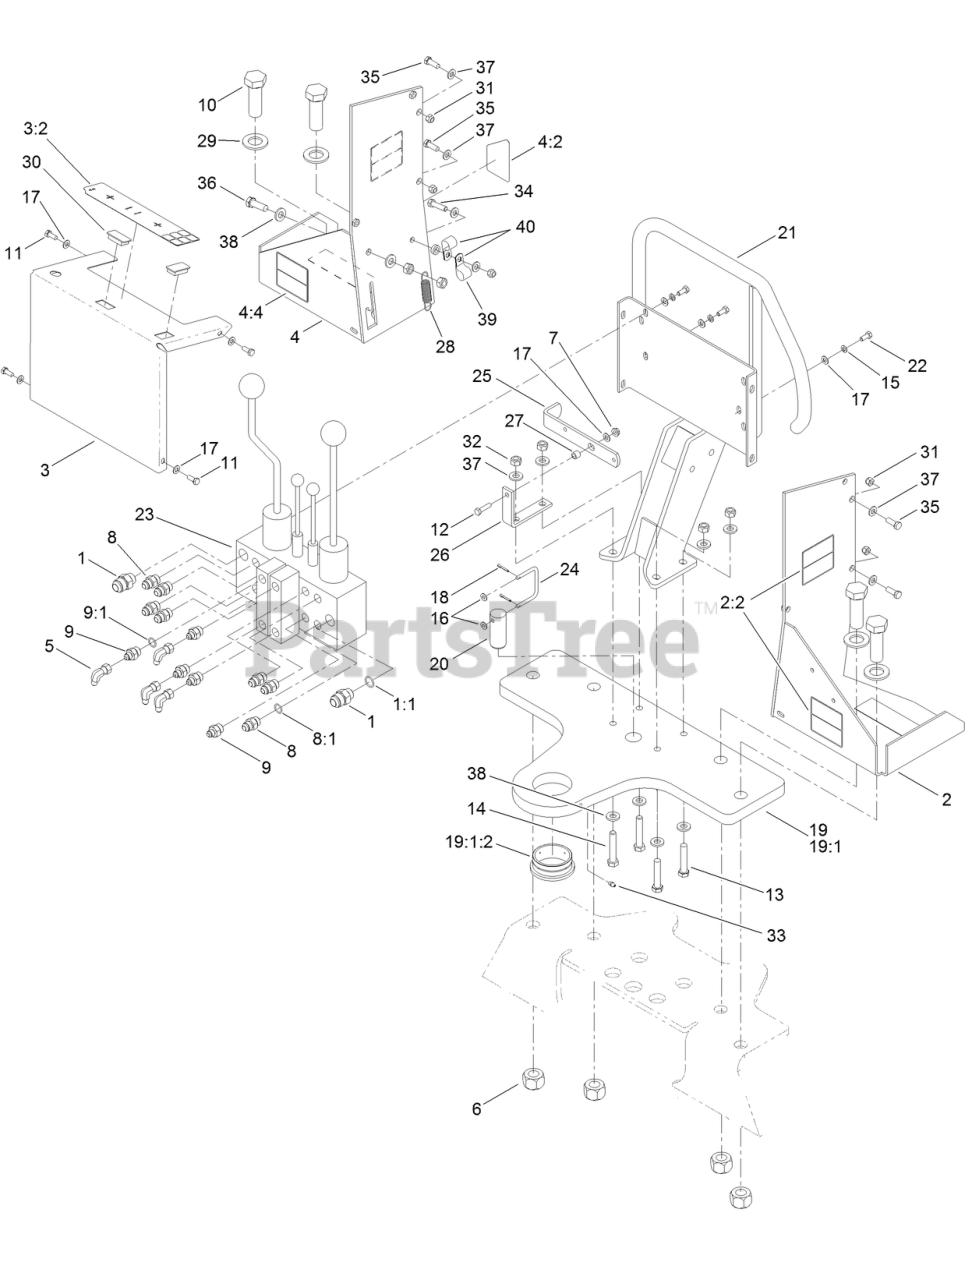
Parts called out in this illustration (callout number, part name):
1	FITTING-STRAIGHT
1:1	O-RING
2	LH FOOT GUARD AND DECAL ASM
2:2	DECAL-DANGER, CRUSHING
3	VALVE COVER AND DECAL ASM
3:2	DECAL-OPERATION, BUCKET
4	RH FOOT GUARD AND DECAL ASM
4:2	DECAL-SWING LOCK
4:4	DECAL-DANGER, CRUSHING
5	ELBOW-SWIVEL, 90 DEG
7	NUT-HF
8	FITTING-STRAIGHT
8:1	O-RING
9	CONNECTOR
9:1	O-RING
12	SCREW-HH
13	SCREW-HH
14	SCREW-HH
15	WASHER-LOCK
16	WASHER-FLAT
17	WASHER-HARDENED
18	PIN-COTTER
19	TOP PIVOT PLATE ASM
19:1	PLATE-TOP PIVOT
19:1:2	BUSHING-KING POST
20	PIN-Control Lever
21	CONSOLE-SEAT MOUNT
22	SCREW-HH
23	HYD CONTROL VALVE ASM
27	BUSHING
30	PLUG-HOLE
31	NUT-HEX
32	LOCKNUT
33	FITTING-GREASE
34	SCREW-HH
35	SCREW-HH
36	SCREW-HH
37	WASHER-FLAT
38	WASHER-FLAT
39	CLAMP-R
